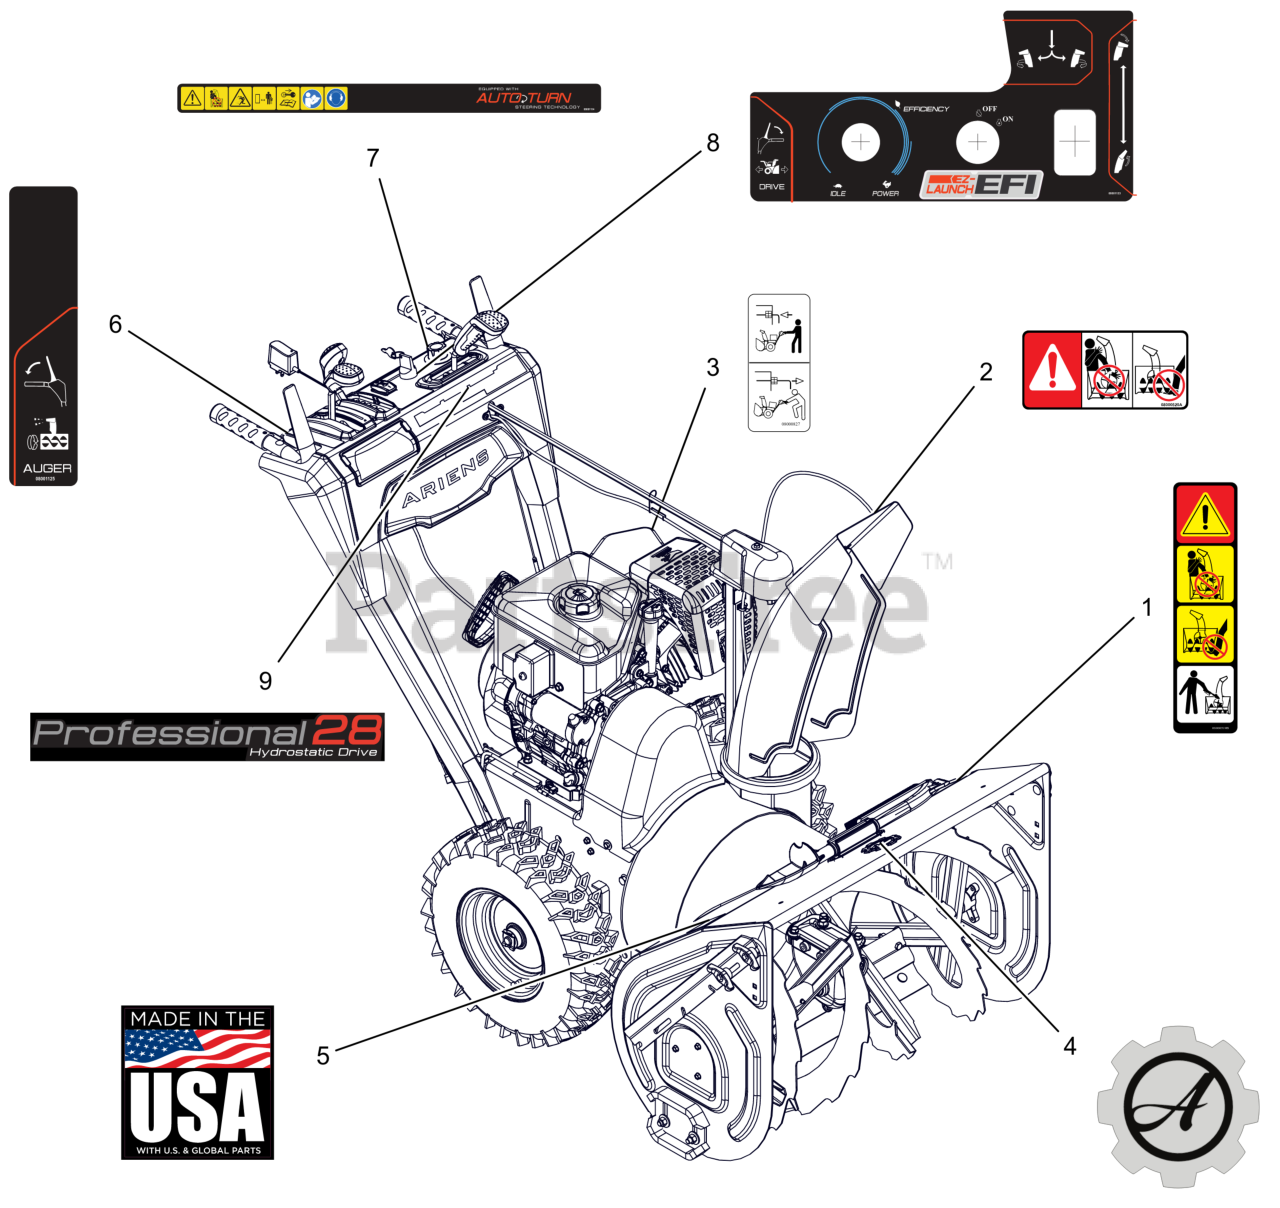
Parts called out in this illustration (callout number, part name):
1	DECAL, DANGER - ROTATING PARTS
2	DECAL, DANGER
3	DECAL, BYPASS
4	DECAL, ARIENS-GEAR BADGE -THK
5	DECAL, MADE IN USA
6	DECAL,CONTROL-RH CONTROL
7	DECAL,DASH - SAFETY/EFI
8	DECAL, CONTROL - QT EFI W/GEL
9	DECAL, DASH - PRO HYDRO 28
